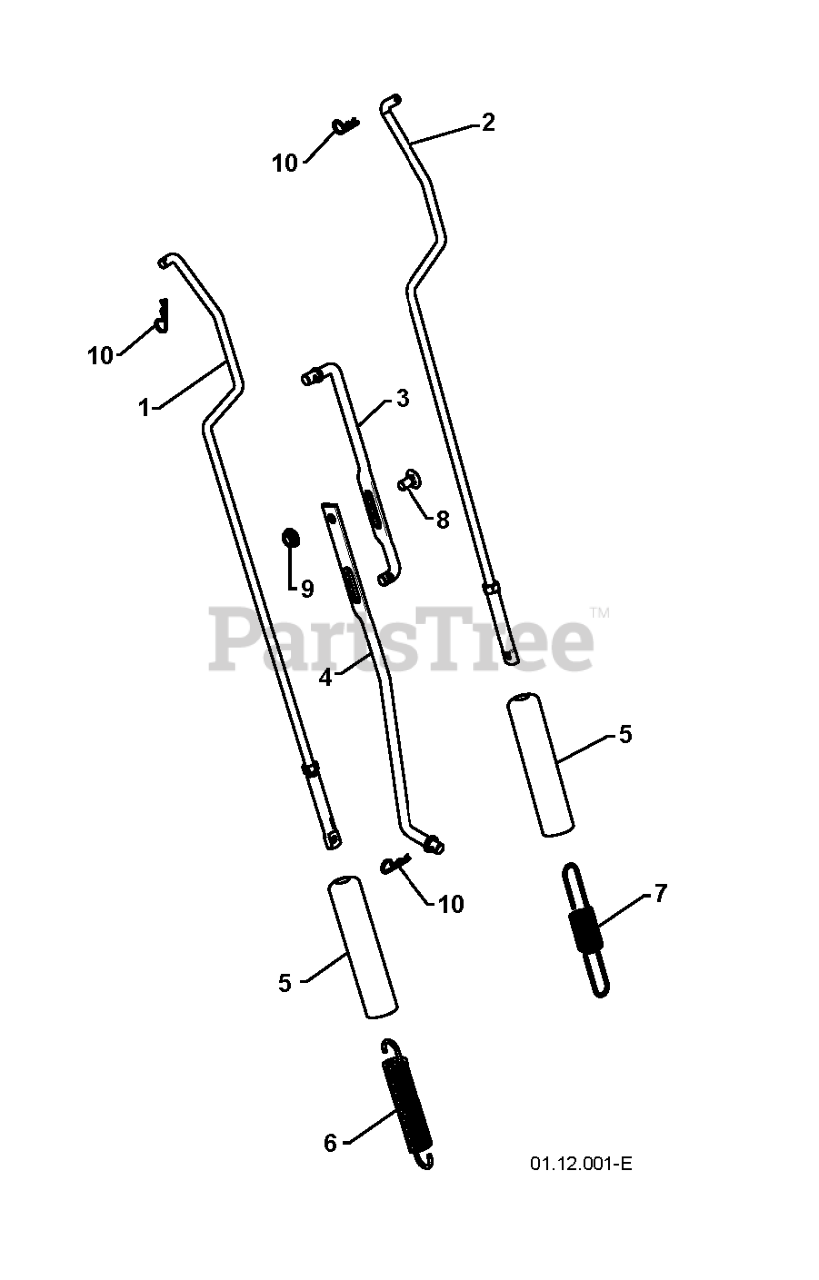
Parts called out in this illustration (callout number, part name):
1	ROD.ASM.IMPELLER
2	ROD.ASM.TRACTION
3	ROD, UPPER SPEED CONTROL
4	ROD, LOWER SPEED CONTROL.SNOW
5	SLEEVE, SPRING
6	SPRING, AUGER CONTROL
7	SPRING, TRACTION DRIVE
8	BOLT
9	NUT.FLANGE.5/16
10	SPRING RETAINER
